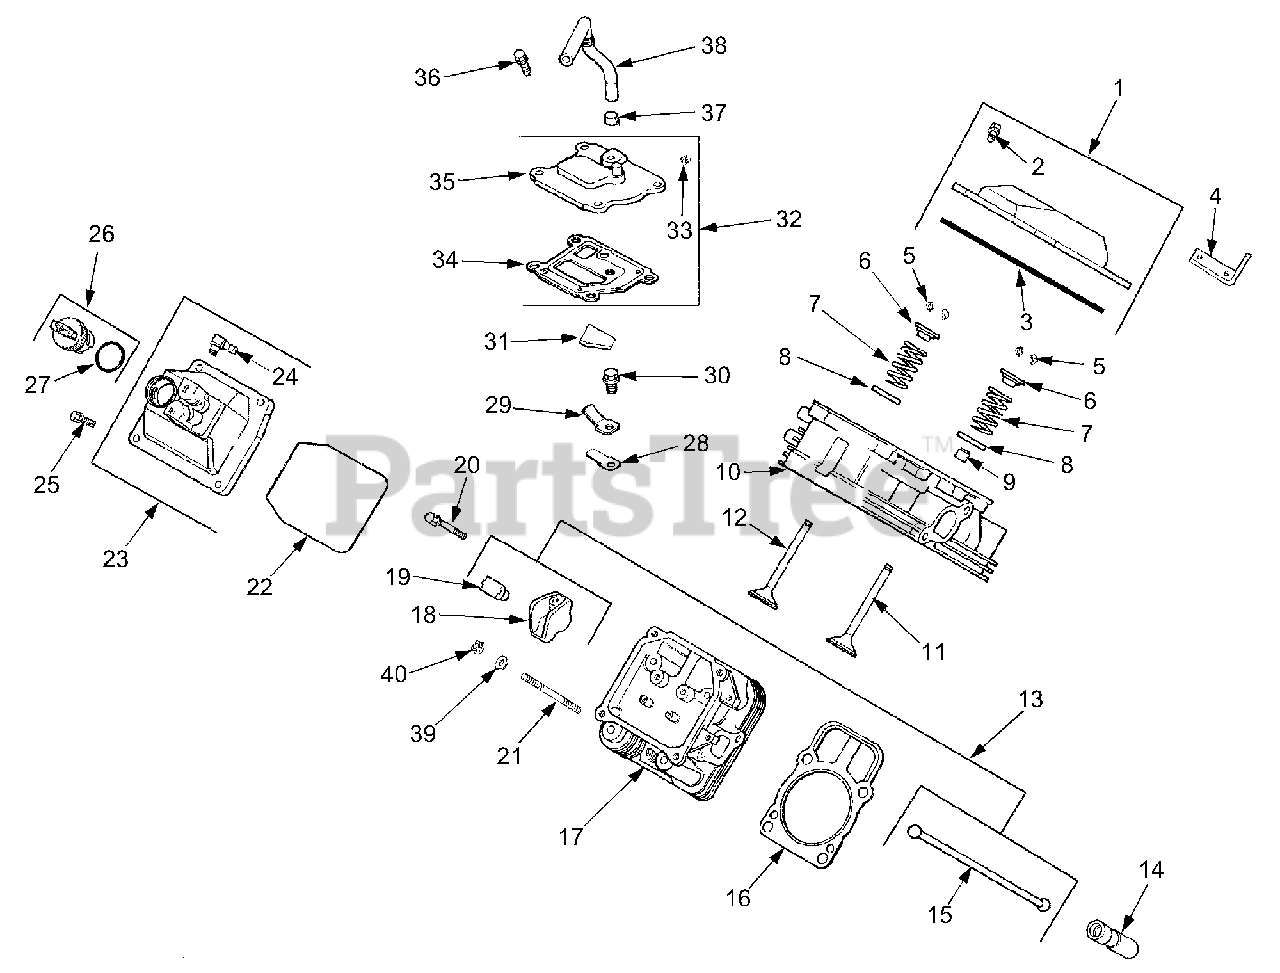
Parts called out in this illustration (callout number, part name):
1	Kit, Valve Cover
2	Screw, Shoulder
3	O-Ring, Valve Cover
4	Strap, Lifting
5	Kit, Retainer
6	Cap, Valve Spring
7	Spring, Valve
8	Retainer, Spring
9	Seal, Valve Stem
10	Head Assembly, #1 Cylinder
11	Valve, Intake (Std.)
12	Valve, Exhaust (Std.)
13	Kit, Valve Train
14	Lifter, Valve
16	Gasket, Cylinder Head
17	Head Assembly, #2 Cylinder
19	Pivot, Rocker Arm
20	Screw, Hex Flange M6 x 1 x 34
21	Stud, Cyl. Hd
22	O-Ring, Valve Cover
23	Cover, Fuel Pump Valve
24	Connector 90°.
25	Screw, Shoulder
26	Cap Assembly, Oil Fill
27	O-Ring
28	Reed, Breather
29	Retainer, Breather Reed
30	Screw, Hex Flange M5 x 0.8 x 10
31	Filter, Breather
32	Kit, Breather
33	Plug, Allen Head 1/8 NPTF
34	Gasket, Breather
35	Cover, Breather
36	Screw, Hex Flange M6 x 1.0 x 20
37	Clamp, Breather
38	Hose, Breather
39	Washer, Flat, 8mm
40	Nut, Hex Flange, M8 x 1.25
